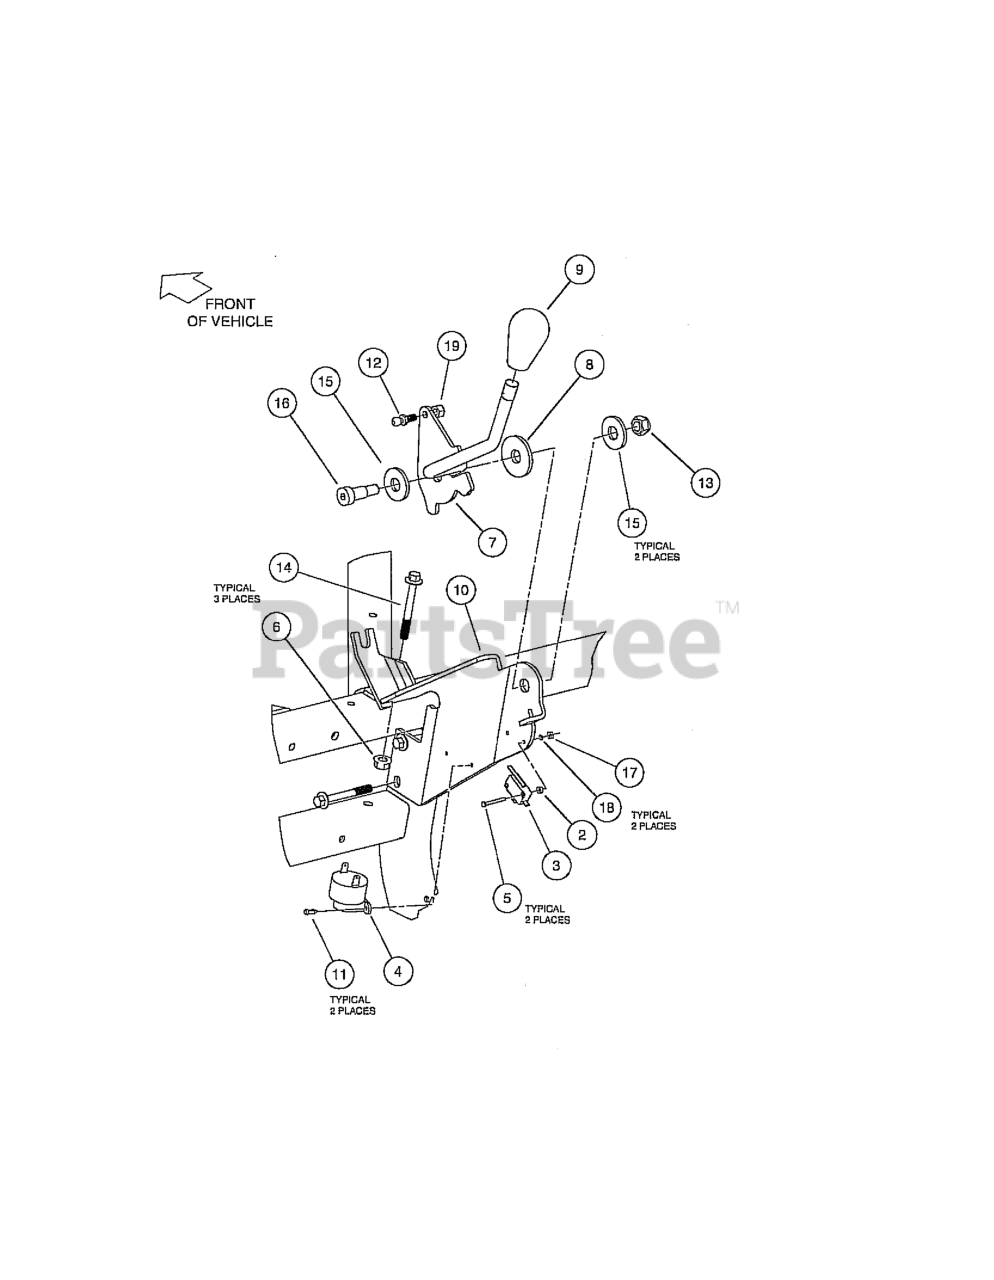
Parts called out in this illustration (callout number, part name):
3	SWITCH,LIMIT
4	BUZZER, 9-48 VDC REVERSE
5	SCREW, #4-40 X 1.125 HX HD MCH
6	NUT, M8, ALL METAL LOCK
8	BUSHING, FNR
12	STUD, BALL, .346 DIA
13	LOCKNUT-M10X1.5
14	BOLT FLG, M8X1.25X65
15	WASHER, M12 HARD REGULAR
16	SHOULDER BOLT,M12 X 20 M10 THD
17	NUT HEX MACHINE
18	LOCKWASH, # 4 HELICAL SPLIT
19	LOCKNUT, 1/4-28 NYLON INSERT
